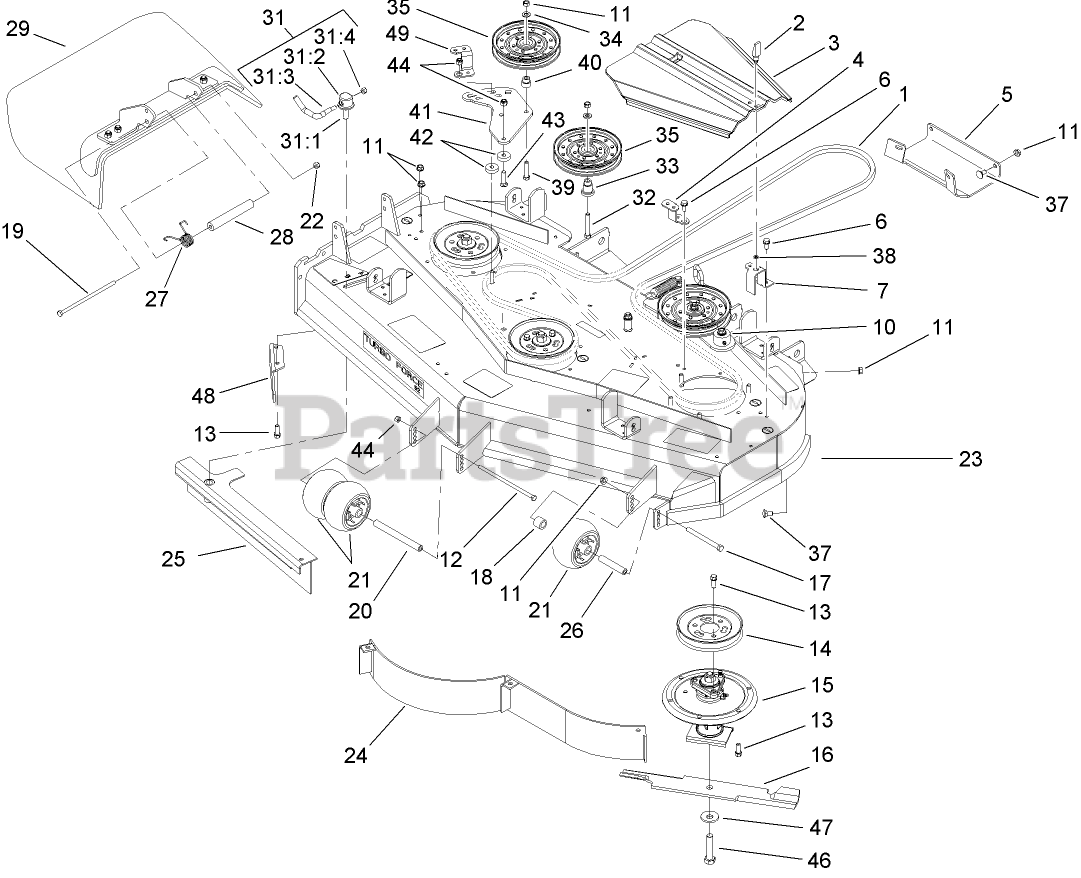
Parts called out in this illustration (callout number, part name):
1	BELT-V
2	LATCH-SWELL
3	COVER-BELT
4	BRACKET-COVER, TALL
5	Plate-Skid
6	SCREW-HWHTF
7	BRACKET-COVER
10	SPRING IDLER ASM
11	NUT-HHF, WHIZ
12	SCREW-HH
13	SCREW-HWH
14	PULLEY
15	SPINDLE ASM
16	BLADE-18IN, HI FLOW
17	SCREW-HH
18	TUBE-SPACER
19	SCREW-HH
20	SPACER-WHEEL
21	ROLLER-SCALP, ANTI
22	NUT-LOCK, NI
23	DECK DECAL ASM
26	TUBE-SPANNER
27	SPRING-TORSION
28	SPACER
29	RUBBER DEFLECTOR ASM
31	LEVER ASM
31:1	Screw-Lock
31:2	CAP-LOCK
31:3	Lever-Lock
31:4	NUT-LOCK, NI
32	SCREW-HH
33	MOUNT-PULLEY
34	WASHER-FLAT
35	Idler-Flat
37	SCREW-CARR
38	WASHER
39	SCREW-HH
40	BUSHING-IDLER
41	PLATE-IDLER
42	Spacer
43	SCREW-CARR
44	NUT-LOCK, NI
46	Screw-Cap
47	Washer-Blade Bolt, Heavy
48	BAFFLE-DISCHARGE
49	BRACKET-COVER, SHORT
99	BLADE-RECYCLER
99	BLADE-LOW FLOW
